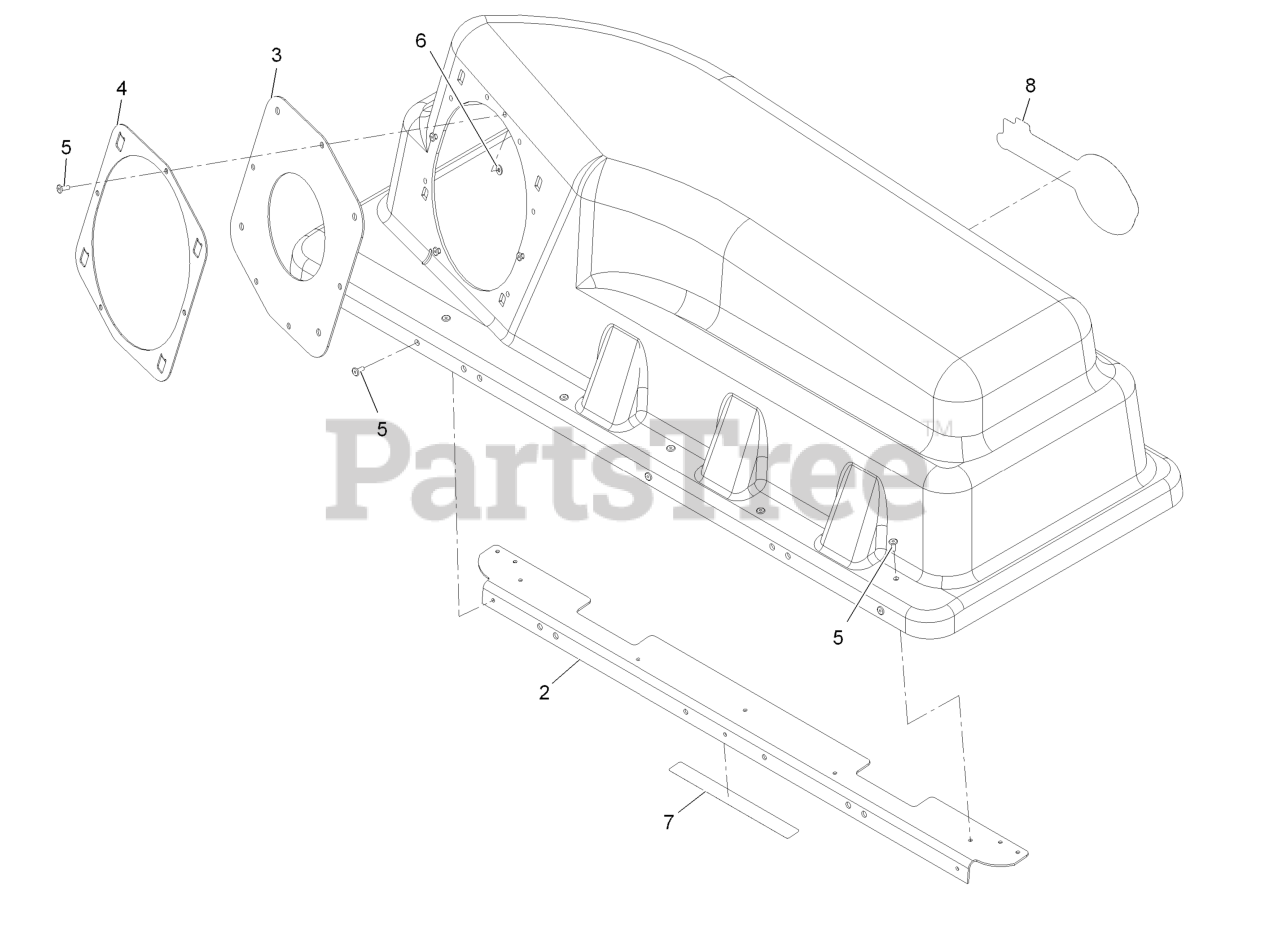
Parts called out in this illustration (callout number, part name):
2	STIFFENER-BAGGER, TOP
4	RING-RETAINER
5	RIVET-BLIND
6	WASHER-FLAT
7	DECAL-CAUTION, BAGGER
8	DECAL-EXMARK LOGO
